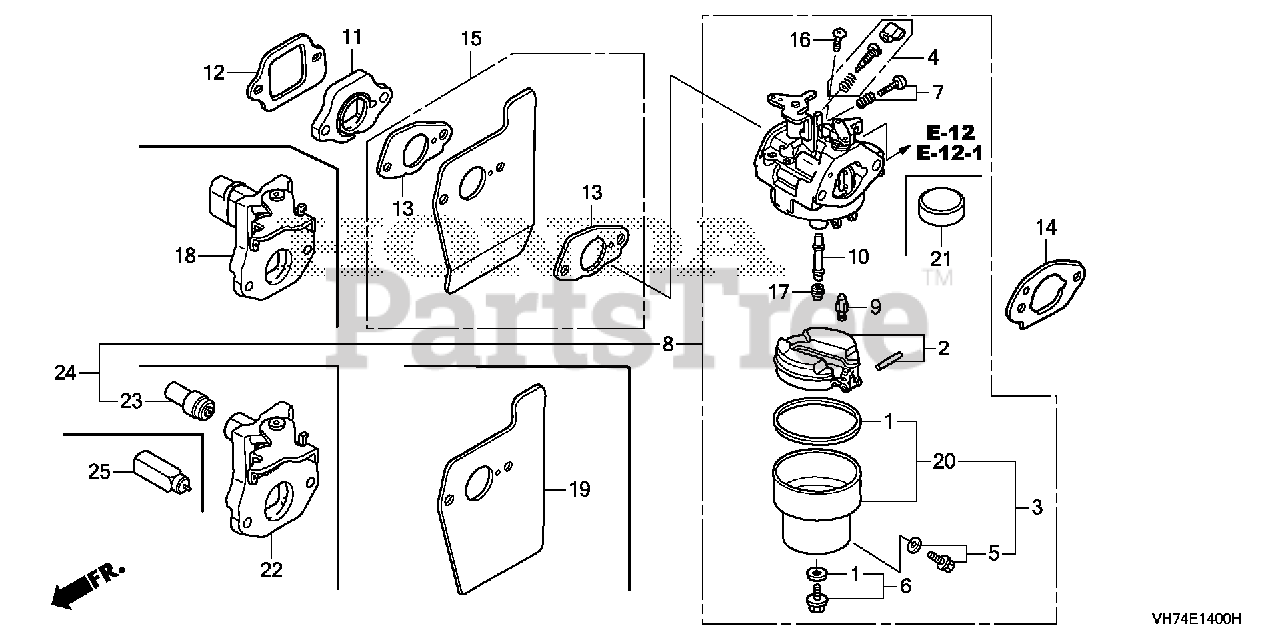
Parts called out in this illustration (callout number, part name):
1	GASKET SET
3	CHAMBER SET, FLOAT (CARBURETOR NO.)
4	SCREW SET (CARBURETOR NO.)
5	SCREW SET, DRAIN (CARBURETOR NO.)
6	SCREW SET
7	SCREW SET (THROTTLE STOP)
8	CARBURETOR ASSY. (BB65B B)
8	CARBURETOR ASSY. (BB65B C)
9	VALVE, FLOAT (CARBURETOR NO.)
10	NOZZLE, MAIN (CARBURETOR NO.)
11	INSULATOR, CARBURETOR
12	GASKET, INSULATOR
13	GASKET, CARBURETOR
14	GASKET, CARBURETOR
15	GUIDE, AIR
16	SCREW, PAN (5X6)
17	JET, MAIN (#65) (CARBURETOR NO.)
17	JET, MAIN (#68) (CARBURETOR NO.)
17	JET, MAIN (#70)
19	GUIDE, AIR
20	CHAMBER SET, FLOAT (CARBURETOR NO.)
